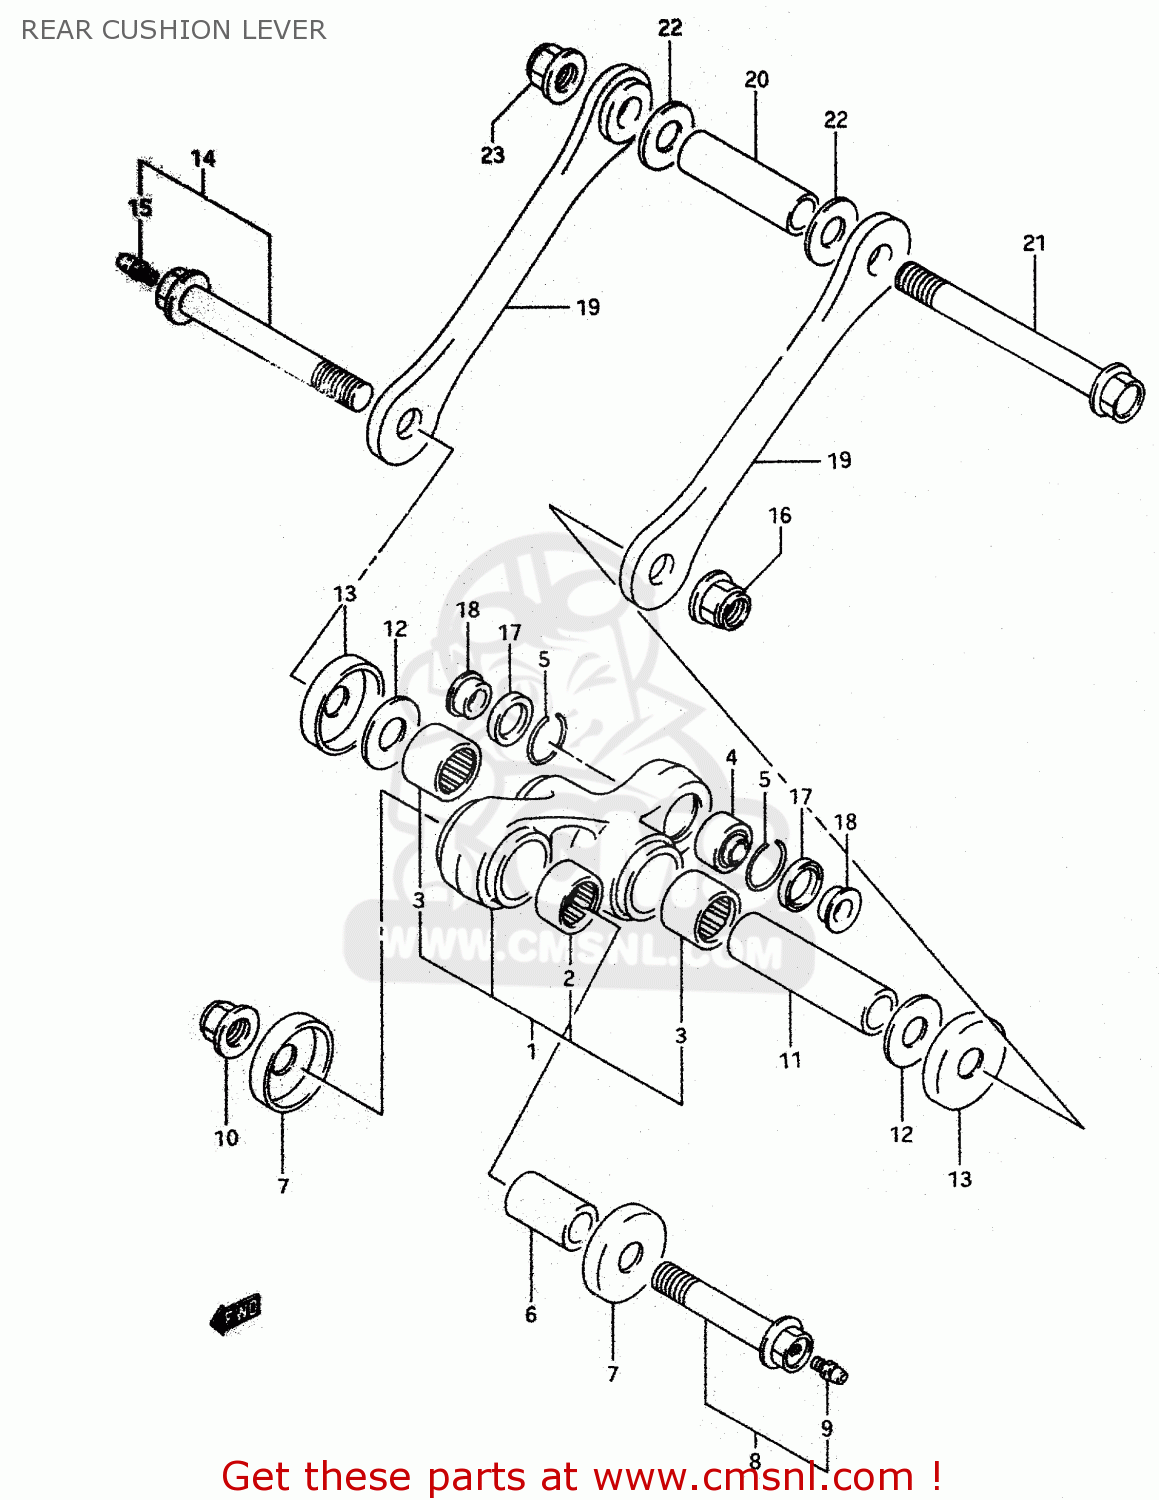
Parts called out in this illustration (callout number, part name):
1	LEVER SET,RR CUSHION
2	BEARING(20X27X32)
3	BEARING(20X27X23.5)
4	BEARING,RR CUSHION LEVER
5	RING,STOPPER
6	SPACER,RR CUSHION LEVER FR
7	SEAL,RR CUSHION LEVER FR DUST
8	BOLT,RR CUSHION LEVER FR
9	GREASE NIPPLE
10	NUT 12MM
11	SPACER,RR CUSHION LEVER CTR
12	WASHER
13	SEAL,RR CUSHION LEVER
14	BOLT,RR CUSHION LEVER CTR
15	GREASE NIPPLE
16	NUT
17	SEAL,REAR DUST
18	COLLAR
19	ROD,RR CUSHION
20	SPACER,RR CUSHION ROD
21	BOLT,RR CUSHION ROD
22	WASHER
23	NUT
